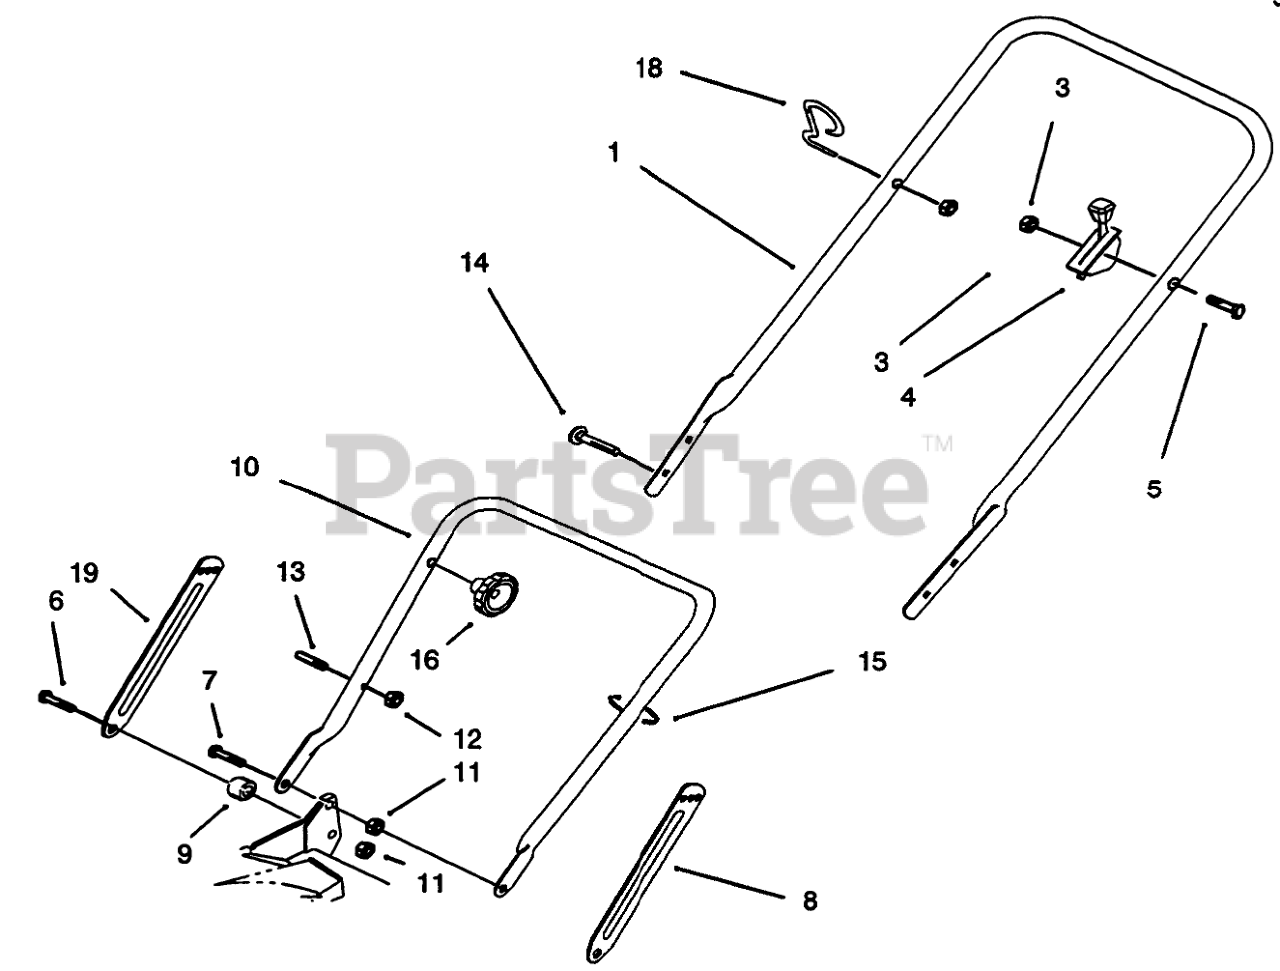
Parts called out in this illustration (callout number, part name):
1	UPPER HANDLE
3	NUT-LOCK, NI
4	THROTTLE CONTROL
5	SCREW-HH
6	SCREW-SHOULDER
7	SCREW-SHOULDER
8	LH HANDLE LATCH
9	SPACER
10	LOWER HANDLE ASM
11	NUT-LOCK, NI
12	NUT-LOCK, NI
13	HANDLE PIN
14	SCREW-HANDLE
15	TIE-CABLE
18	GUIDE-ROPE
19	RH HANDLE LATCH
